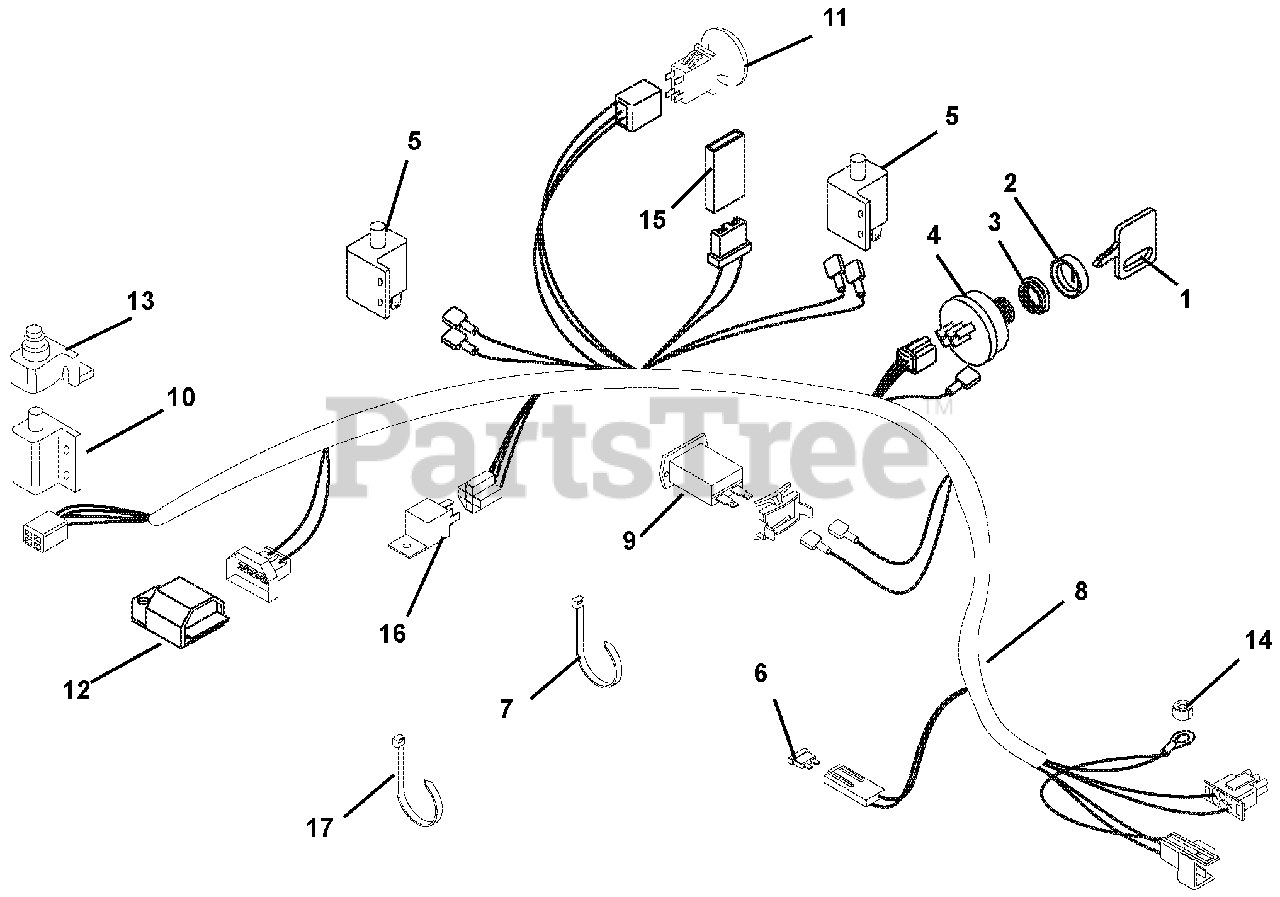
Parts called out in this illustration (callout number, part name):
1	Key- with Cap
2	Cap, Ignition Switch
3	Nut, Panel .562-24
4	Key Switch
5	Switch- Double Pole N.O./N.O.
6	Fuse-25 AMP
7	Tie Wrap-Black
8	Wire Harness-Hydro Recoil-Pro Steer
9	Hour Meter-Quartz
10	Switch, Interlock
11	Switch- PTO- NMIR
12	Module, Interlock Recoil
13	Boot, Rubber
14	Nut-Locking-Top-Flange .31-18
15	Diode, Connector Shell
16	Relay
17	Tie Wrap
